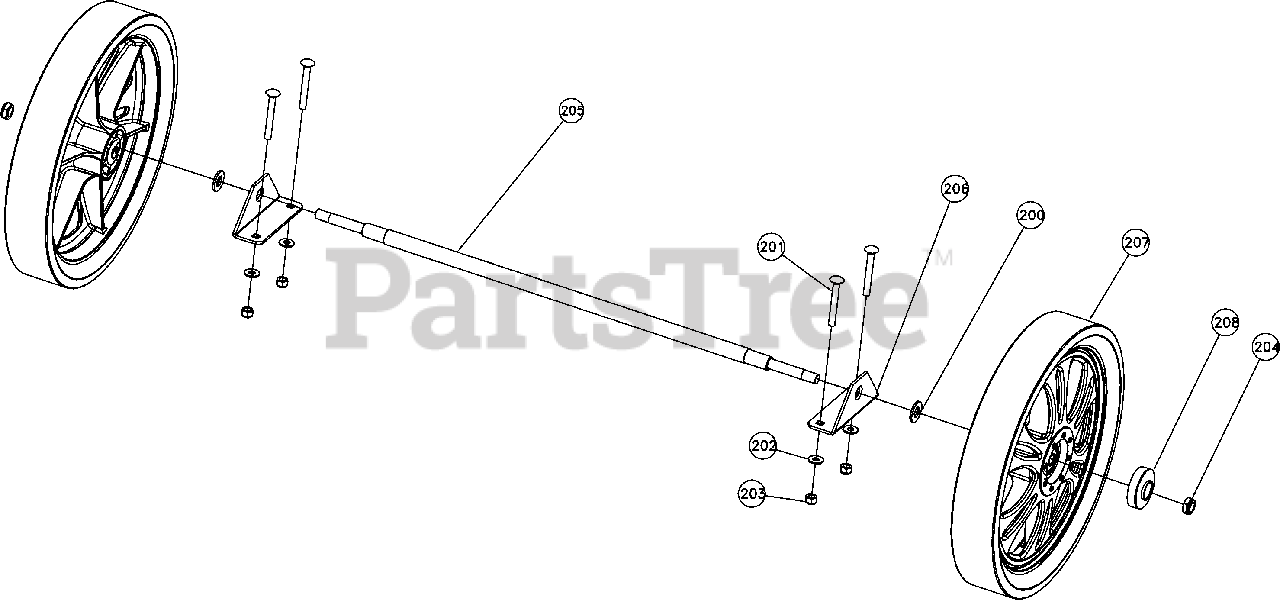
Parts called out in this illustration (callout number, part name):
200	WASHER FLAT 1/2" SAE
201	BOLT CARRIAGE 5/16-18X2 1/2
202	WASHER 1/4" FC ZP
203	NYLON INSERT LOCKNUT 5/16-18 UNC
204	NYLON INSERT LOCKNUT 1/2-13 UNC THIN
205	SHAFT REAR AXLE PUSH VAC
206	BRACKET REAR AXLE MOUNT PUSH MV VAC
207	WHEEL 14" ASSEMBLY WITH BEARING AND TIRE
208	MV WHEEL BEARING
